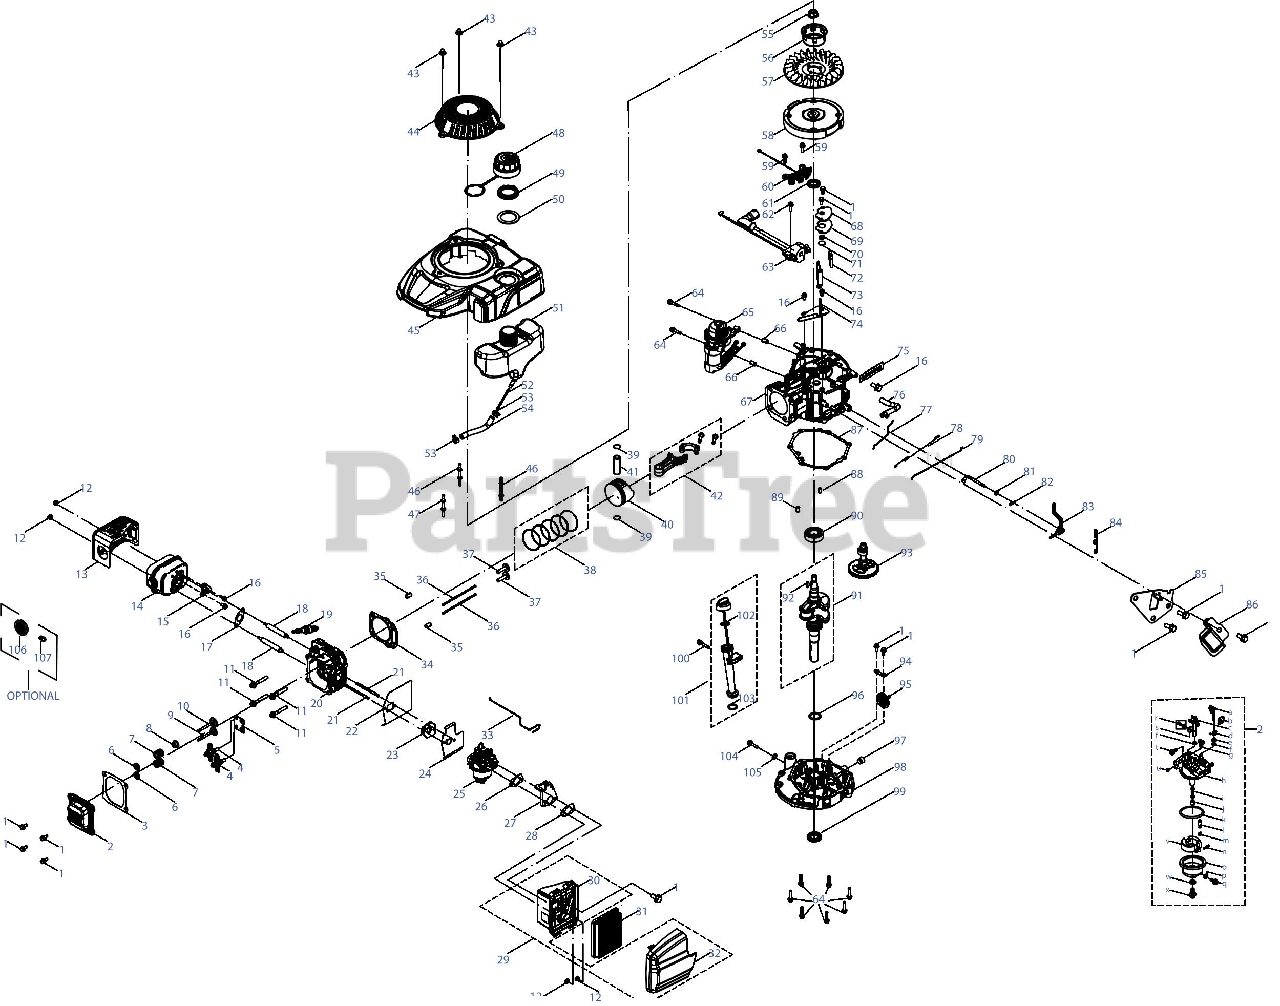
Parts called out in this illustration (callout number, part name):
1	Bolt M6x14
2	Valve Cover
3	Valve Cover Gasket
4	Rocker Arm Assembly
5	Push Rod Guide
6	Valve Spring Retainer
7	Valve Spring
8	Intake Valve Seal
9	Exhaust Valve
10	Intake Valve
11	Bolt M8x54 Cylinder Head
13	Muffler Shield
14	Muffler Assembly
15	Choke Thermal Control
16	Bolt M6x12
17	Muffler Gasket
18	Muffler Stud M6x95
19	Spark Plug/F5RTC
20	Cylinder Head
21	Carb Stud M6x87
22	Carburetor Insulator Gasket
23	Carburetor Insulator
24	Carburetor Gasket
25	Carburetor Assembly
26	Air Filter Bracket Gasket
27	Air Filter Bracket
28	Air Filter Base Gasket
29	Air Filter Assembly
30	Air Filter Base
31	Air Filter Element, Paper
32	Air Filter Cover
33	Temp Control Linkage
34	Cylinder Head Gasket
35	Cylinder Head Dowel Pin 10x16
37	Tappet
38	Piston Ring Set
39	Piston Pin Snap Ring
41	Piston Pin
42	Connecting Rod Assembly
43	Starter Acorn Nut
44	Starter Cover Housing
45	ENGINE SHROUD ASSEMBLY
46	Shroud Stud M6x78.5
47	Shroud Stud M6x74
48	Fuel Cap Assembly
49	Fuel Tank Nut
50	Fuel Tank Upper Grommet
51	Fuel Tank
52	Fuel Filter
53	Fuel Hose Clamp
54	Fuel Hose
55	Flywheel Nut M14
56	Starter Cup
57	Cooling Fan
59	Bolt M6x20
60	Alternator
61	Upper Crankshaft Seal
62	Bolt M6x25
63	Ignition Coil Assembly
64	Bolt M6x28
65	Electric Starter Assembly (69:12)
66	Starter Housing Dowel Pin 8x8
68	Breather Cover Plate
69	Breather Gasket
70	Breather Valve Spring
71	Breather Valve
72	Breather Screen
73	Air Vane
74	Air Vane Bracket
75	Flexible Clamp
76	Breather Hose Assembly
77	Choke Linkage
78	Throttle Linkage
79	Throttle Linkage Spring
80	Governor Arm Shaft
81	Governor Seal
82	Governor Arm Shaft Cotter Pin
83	Governor Arm Assembly
84	Governor Spring
85	Component Bracket
86	Governor Shield
87	Crankcase Cover Gasket
88	Crankcase Cover Dowel Pin 7x14
89	Crankcase Cover Dowel Pin 9x14
90	Main Bearing
91	Crankshaft Assembly
92	Flywheel Key
93	Camshaft Assembly
94	Governor Gear Mounting Plate
95	Governor Gear/Shaft Assembly
96	Crankshaft Thrust Washer
97	Oil Drain Plug
98	Crankcase Cover
99	Lower Crankshaft Seal
100	Bolt M6x35
101	Dipstick Assembly
102	Dipstick / Oil Fill Tube O-Ring
103	Dipstick / Oil Fill Tube O-Ring
104	Oil Drain Plug
105	Oil Drain Plug Washer
106	Spark Arrestor
107	Spark Arrestor Screw
